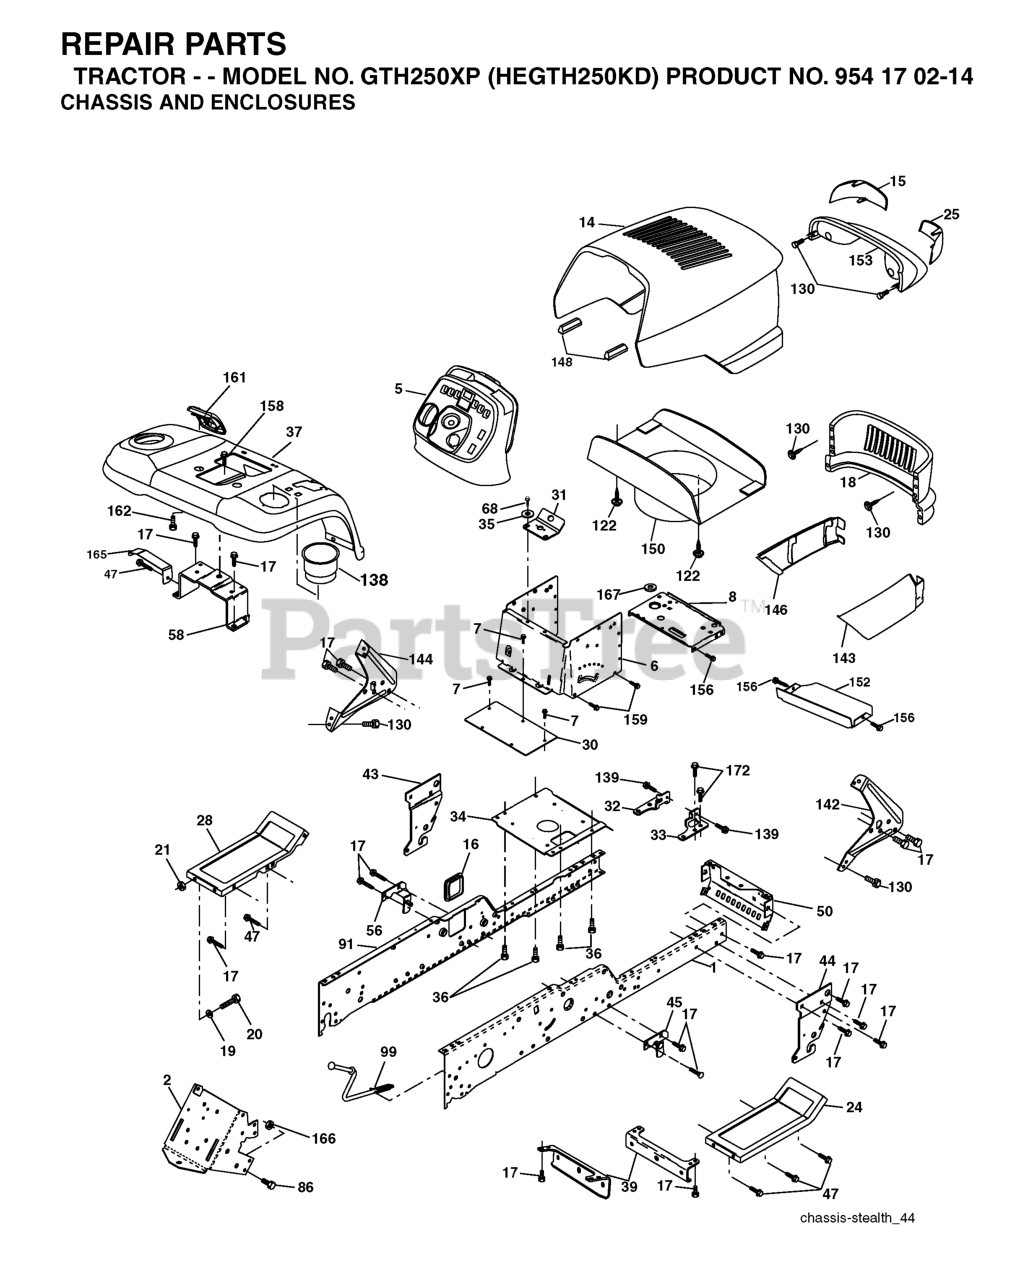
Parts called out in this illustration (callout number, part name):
1	KIT.RAIL.CHASS.RH.GT
2	DRAWBAR, GT
6	DASH VGT, LOWER
7	SCREW
8	SUPPORT, BATTERY
14	HOOD
15	LENS LH
16	COVER ACCESS
17	SCREW, 3/8-16X3/4
18	GRILLE.STEALTH P/L.YTGT.GREY
19	WASHER
21	NUT
24	FOOTREST PNT RH
25	LENS RH
28	FOOTREST PNT LH
30	SADDLE.HYDRO.95
31	BRACKET SUPT 1-PC VGT STEERING
34	PLATE ASM ENG CHASSIS
35	WASHER
36	SCREW 5/16"
37	FENDER, PNT
39	BRACKET AXLE, FRONT
43	FRONT SUSPENSION BRKT LH
44	FRONT SUSPENSION BRKT RH
45	BRACKET, ASM., SUSP CHASSIS RH
50	BRACKET, CHASSIS FRONT
56	BRACKET ASM., SUSP CHASSIS LH
58	BRACKET ASM., FENDER
68	Screw 5/16-18 x 1/2 Hex, Self Tapping 5/16-18 x 1/2
86	BOLT FIN HEX 7/16-14 X 1
91	KIT.RAIL.CHASS.LH.GT
99	ROD ASM, BYPASS
122	SCREW.HEX.WS.HD.8-18 X 7/8
130	SCREW
138	CUPHOLDER
139	BOLT, SHOULDER 5/16-18
142	BRACKET DASH STEALTH(R)
143	SKIRT GRILLE RH
144	BRACKET DASH STEALTH LH
146	SKIRT GRILLE LH
148	EXTRUSION BUMPER (3 2) (2 2)
150	DUCT.HEAT.HOOD.STEALTH.GT
152	BROWNING SHIELD
153	LIGHTBOX.ASM.STV.DL.INC.HUSQ
156	SCREW
158	SCREW 3/8-16X1/2
159	SCREW, 3/8-16X3/4
161	CONSOL.FUEL.WINDOW.BLACK
162	SCREW.HI-LO.CONSOLE
165	BRACKET SUPPORT TANK
166	Nut, Crownlock Hex 7/16-14 unc
167	BUSHING SNAP
172	SCREW 3/8-16X.875
